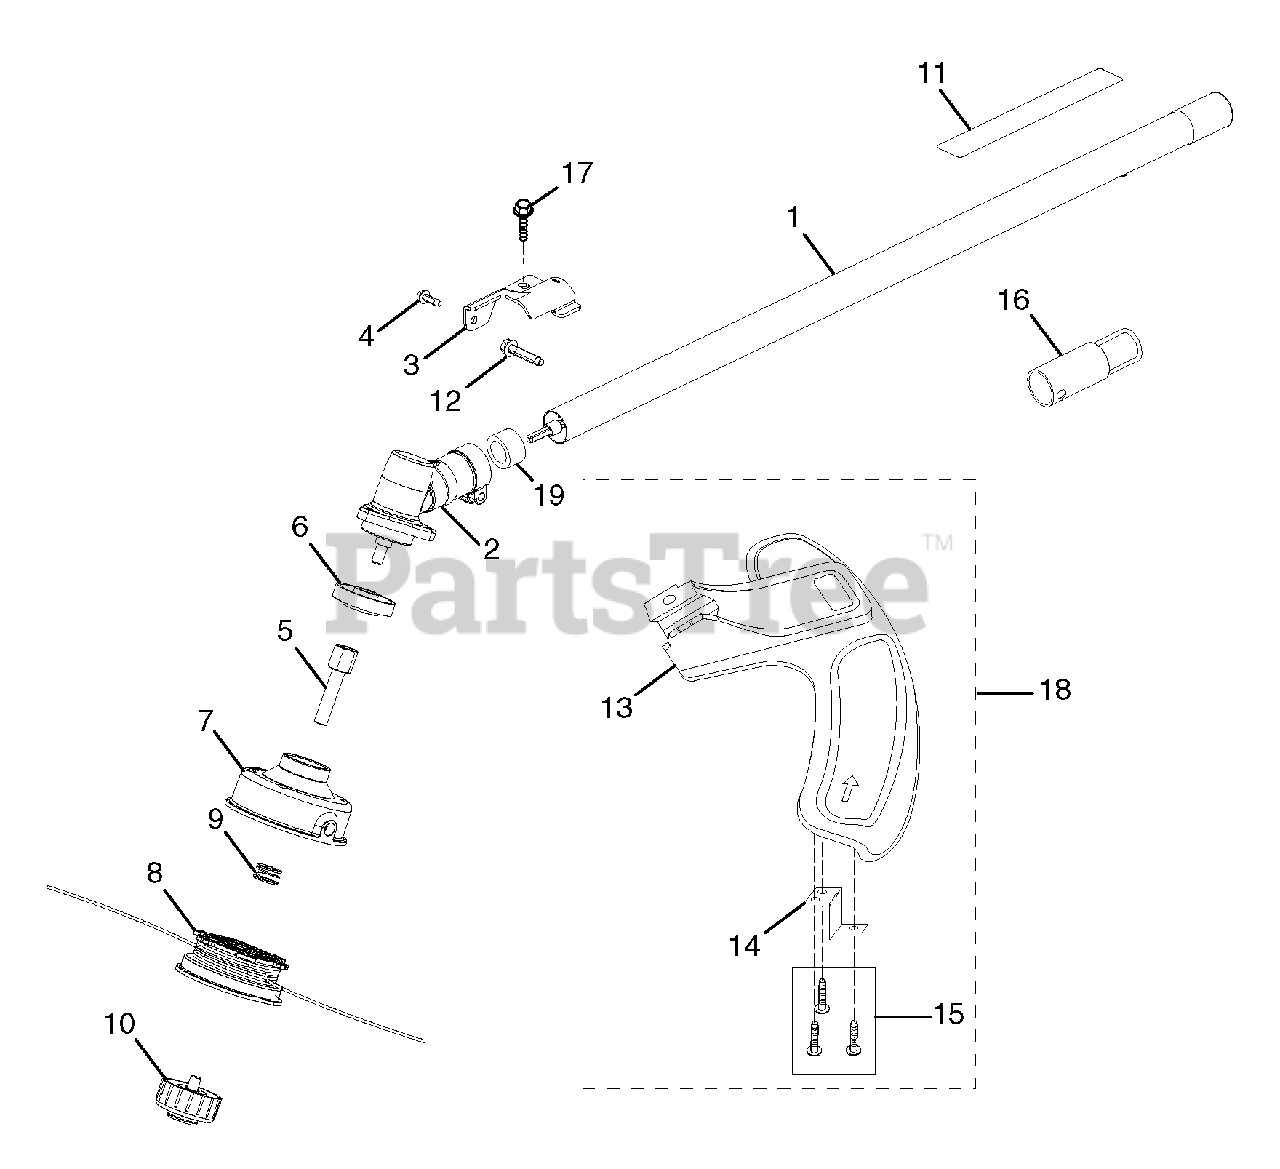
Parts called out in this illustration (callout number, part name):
1	Straight Shaft Assembly
2	Gear Case Assembly
3	Grass Deflector Clamp
4	Screw(#10-24 x 5/8 in. Hex Washer Head, Tri-
5	Trimmer Head Shaft Adaptor
6	Flanged Washer
7	Trimmer Head
8	Spoolwith Line (.095)
9	Compression Spring
10	Retaining Cap,Left-handed threads
11	Warning Label
12	Screw(#1/4-20 x 1-1/4 in.Washer Head,Tri-lobular) Hex
13	Grass Deflector
14	Line Cutting Blade
15	Screw(#8-16 x1/2in.Truss Head,Tri-lobular)
16	Storage Cap
17	Screw(#1/4-20 x 1-1/4 in. Hex Washer Head,
18	Grass Deflector Assembly
19	Spacer
